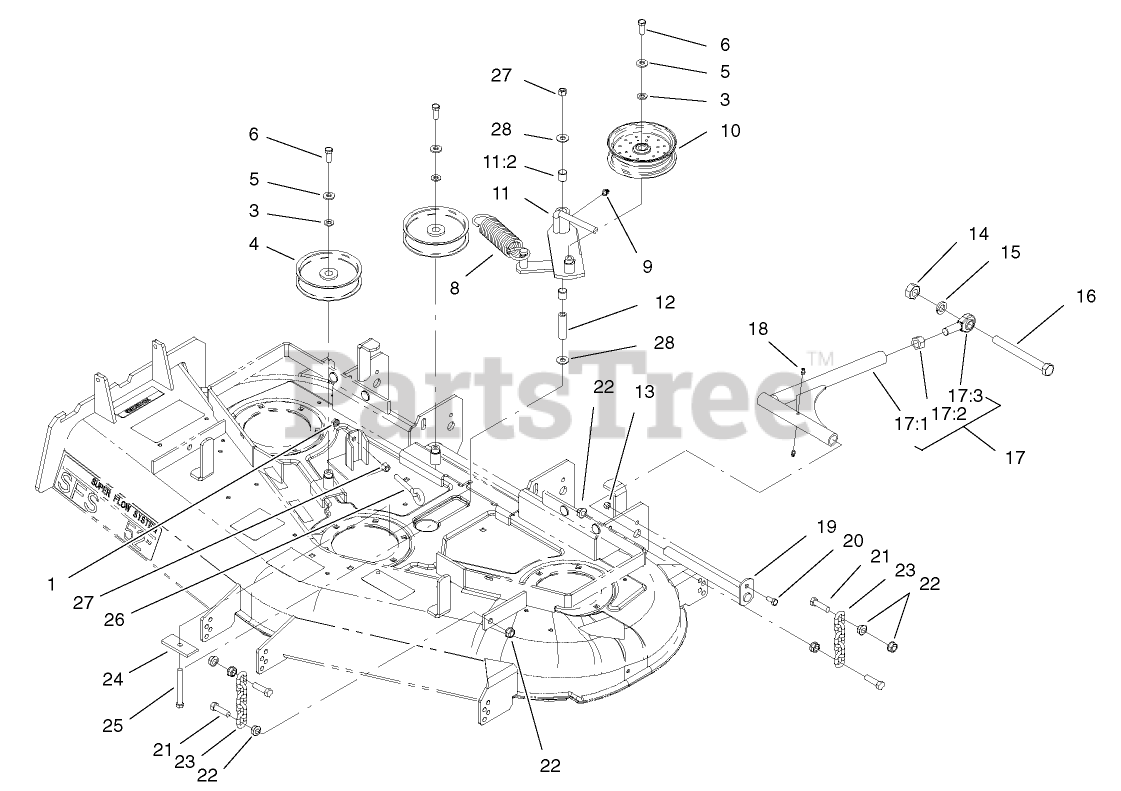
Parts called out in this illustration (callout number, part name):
1	NUT-HEX
3	WASHER-FLAT
4	PULLEY-IDLER
5	WASHER-BELLEVILLE
6	SCREW-HH
8	SPRING-EXTENSION
9	FITTING-GREASE, 90 DEG
10	PULLEY-IDLER
11	IDLER ARM ASM
11:2	SLEEVE-BEARING
12	BUSHING-PIVOT, IDLER
13	NUT-LOCK, NI
14	NUT-HEX
15	WASHER-LOCK
17	STRUT ASM
17:1	STRUT
17:2	NUT-HEX
17:3	BALLJOINT-SPHERICAL
18	FITTING-GREASE
19	PIN-STRUT
20	SCREW-HH
21	SCREW-HH
22	NUT-HF
23	CHAIN-LIFT, DECK
24	PLATE-RETAINER, BOLT
25	SCREW-HH
26	BOLT-EYE
27	NUT-LOCK, NI
28	WASHER-HARDENED
